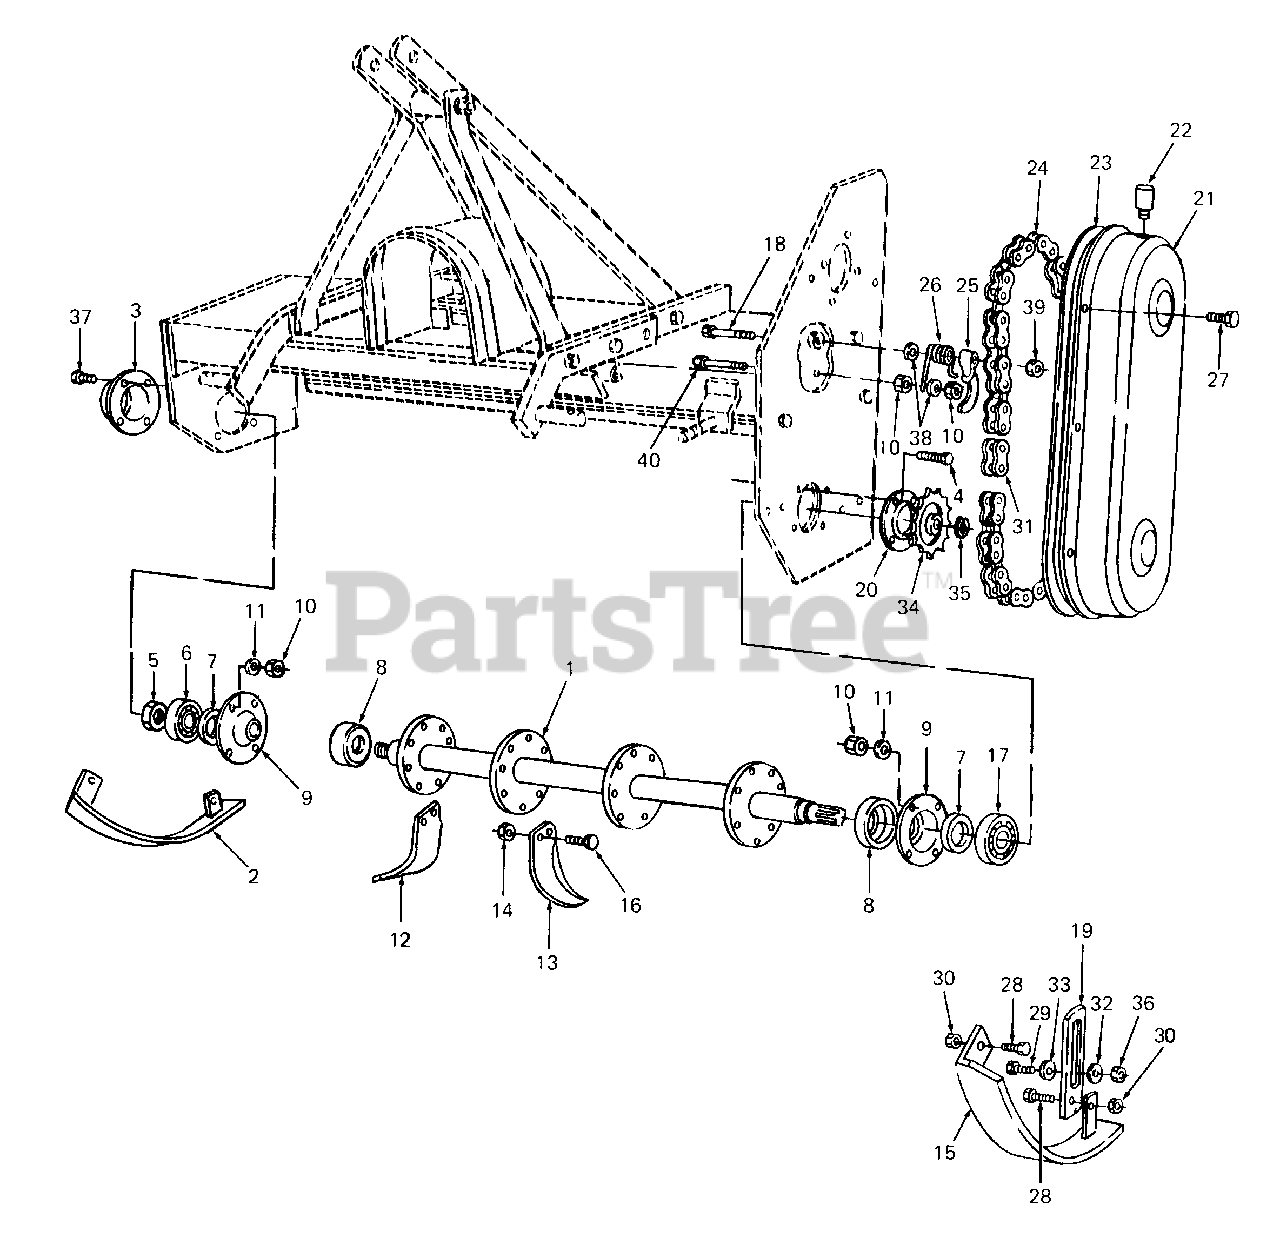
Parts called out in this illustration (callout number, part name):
1	Shaft, Rotor
2	Shoe, RH Skid
3	Cover, RH Bearing
4	Bolt, M10 X 25
5	Nut, Self Locking
6	Bearing, Rotor Shaft RH
8	Shield, Dirt
9	Cover, Inner Bearing
11	Washer, Lock
12	Knife, Right
15	Shoe, LH Skid
16	Bolt, M12 X 30
17	Bearing, Rotor Shaft LH
18	Bolt, M10 X 60
19	Arm, Slotted Adjustment
20	Cover, LH Bearing
21	Housing, Chain & Sprocket
22	Cap, Breather
24	Drive Chain, 45 Links #60
25	Tensioner, Chain
26	Spring, Chain Tensioner
27	Bolt, M10 X 20
28	Bolt, M10 X 30
29	Bolt, M10 X 45
31	Link, #60 Master
32	Washer, Spacer
33	Washer w/Threads, Spacer
34	Sprocket, 22 Tooth
37	Bolt, M10 X 30
38	Washer, Flat
39	Nut, Self Locking, M10
40	Bolt, M10 X 55
